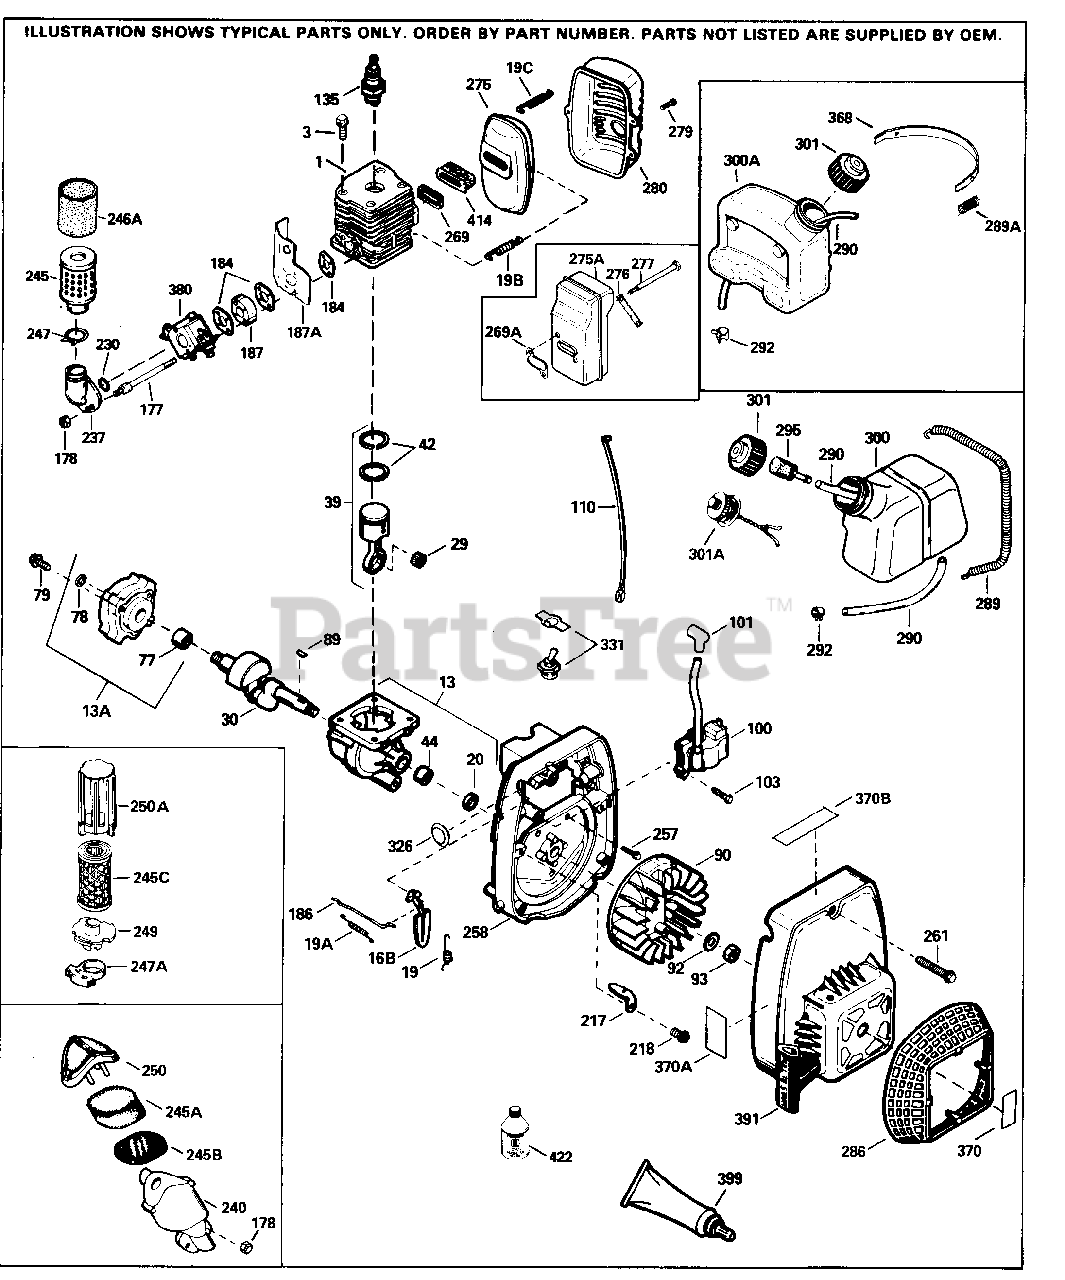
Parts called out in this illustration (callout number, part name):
1	"Cylinder
3	Screw, T-30, 1/4-20 x 43/64
13	Crankcase (Incl. 20 & 44)
13A	Crankcase Cover (Incl. 77 & 78)
16B	Air Vane
19	Governor Spring
19A	Backlash Spring
19B	Muffler Spring
20	Oil Seal
29	Needle Bearing Set (23 needles) NOTE: Bearing 530154 is no longer availabl e. If it is required, the engine must be short blocked. See Engine and Sho rt Block Replacement List.
30	Crankshaft NOTE: Crankshaft 290564 is no longer available. If it is requir ed, the engine must be short blocked. See Engine and Short Block Replaceme nt List.
39	Piston & Rod NOTE: Piston and rod 310 284 is no longer available. If it is required, the engine must be short bl ocked. See Engine and Short Block Rep lacement List.
42	Piston Ring Set
44	Cartridge Bearing
77	Cartridge Bearing
78	Oil Seal
79	Screw, 1/4-20 x 3/4
89	Flywheel Key
90	Flywheel
92	Belleville Washer
93	Flywheel Nut, 3/8-24
100	Solid State (Incl. 101)
101	Spark Plug Cover
103	Screw, T-15, 10-24 x 1
110	Ground Wire
135	Spark Plug (RCJ-6Y)
177	Air Cleaner Stud
178	Lock Nut, 10-24
184	Carburetor Gasket
186	Governor Link
187	Carburetor Spacer
187A	Carburetor Baffle
217	Speed Adjusting Lever
218	Screw, 8-32 x 1/2
230	Air Cleaner "O" Ring
240	Air Cleaner Body
245A	Air Filter
245B	Air Filter
250	Air Cleaner Cover
257	Screw, 10-24 x 1/2
258	Blower Housing Base
261	Screw, 8-32 x 1-9/16
269	Exhaust Gasket
275	Muffler
286	Starter Screen
289A	Fuel Tank Strap Spring
290	Fuel Line (11" long)
292	Fuel Line Clamp
295	Fuel Fitting & Filter Assy.
300A	Fuel Tank (Incl. 290 & 295)
301	Fuel Cap
368	Fuel Tank Strap (Incl. 289A)
370	Name Decal
370A	Instruction Decal
380	Carburetor (Incl. 184) (Refer to Divi sion 5, Section A, page A10-4 or Fich e 24, Grid F-9 for breakdown)
391	Rewind Starter & Housing Assy. Refer to Division 5, Section C, page 33 or Fiche 24, Grid G-1 for breakdown
399	Gasket Eliminator
422	2-Cycle Oil with Fuel Stabilizer - 8 oz.
